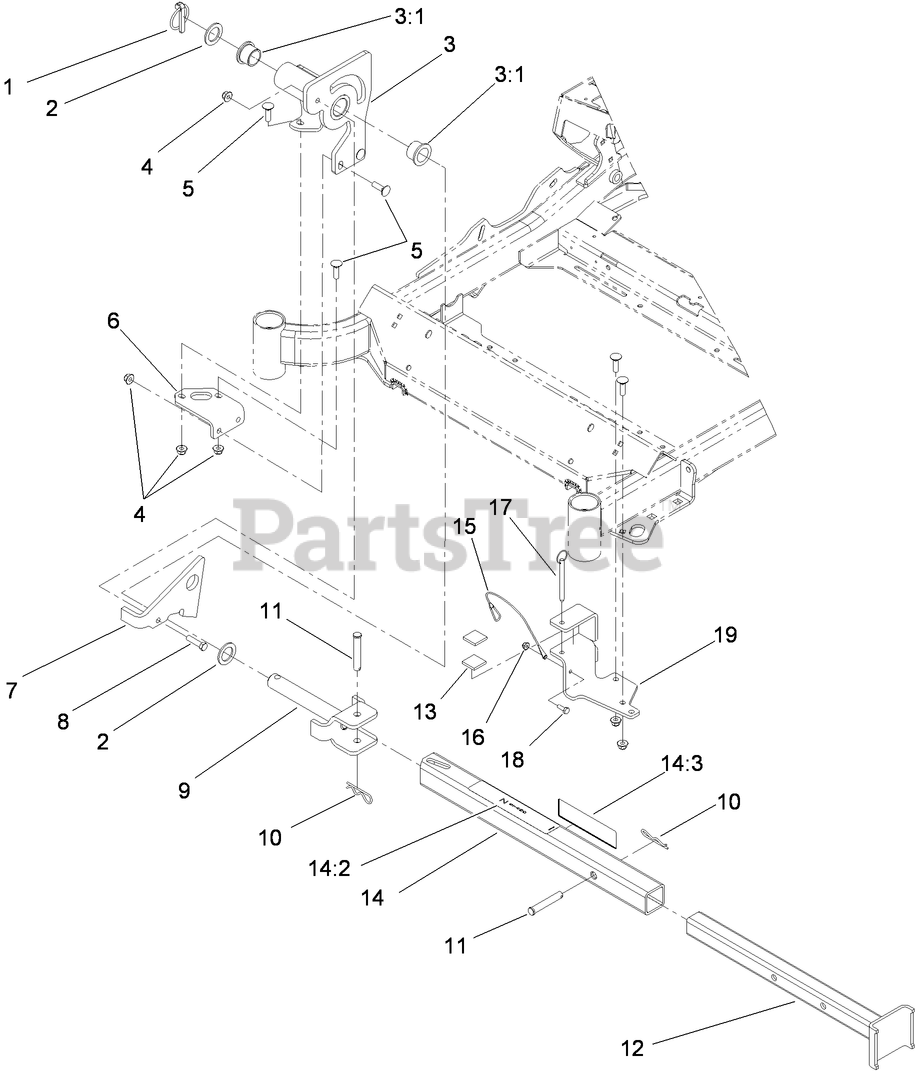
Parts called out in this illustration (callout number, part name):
1	PIN-LYNCH
2	WASHER-THRUST
3	Z STAND PIVOT ASM
3:1	BUSHING
4	NUT-HF, NI
5	BOLT-CARR
6	BRACKET-MOUNT, PIVOT
7	BRACKET-LATCH
8	SCREW-HH
9	PIN-PIVOT
10	PIN-HAIR
11	PIN-CLEVIS
12	TUBE-INNER
13	CUSHION-RUBBER
14	OUTER TUBE ASM
14:2	DECAL-Z STAND
14:3	DECAL-WARNING
15	LANYARD-NYLON
16	NUT-HF
17	PIN-HITCH, COTTERLESS
18	SCREW-HH
19	CRADLE-Z STAND
